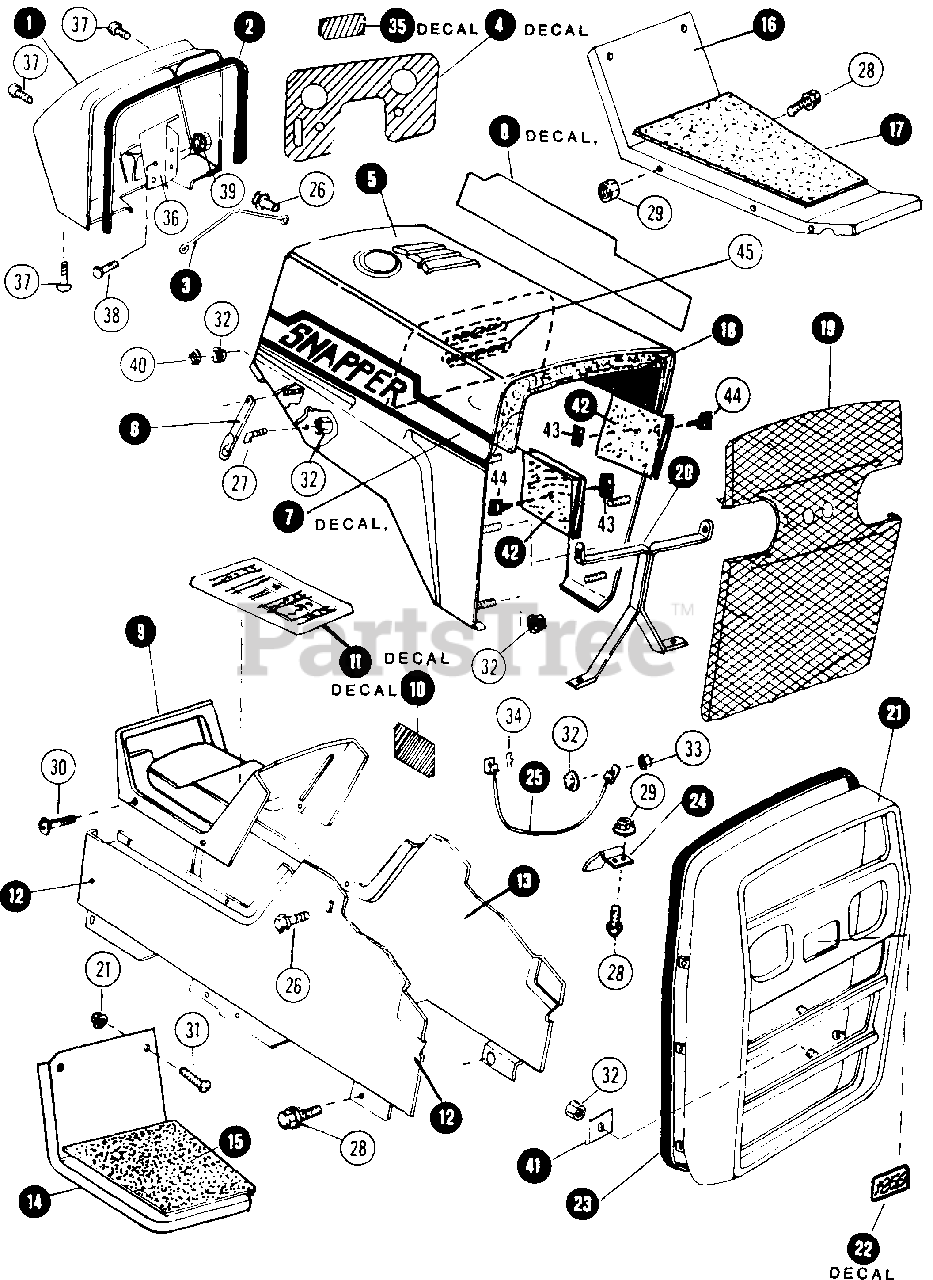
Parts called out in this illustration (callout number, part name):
1	COWL, INSTRUMENT DASH
2	TRIM, COWL MOLDING
3	REINFORCEMENT, COWL
4	DECAL, INSTRUMENT DASH
5	HOOD-PANEL
6	STRAP, HOOD RETAINER
7	DECAL, SNAPPER RIGHT SIDE HOOD
8	DECAL, SNAPPER LEFT SIDE HOOD
9	PANEL, CENTER ACCESS CONSOLE
10	DECAL, CAUTION
11	DECAL, CONSOLE - OPERATING INSTRUCTION
12	PANEL, RIGHT SIDE
13	PANEL, LEFT SIDE
14	PLATE, RIGHT STEP
15	TREAD, RIGHT PLATE
16	PLATE, LEFT STEP
17	TREAD, LEFT STEP PLATE
18	INSULATION, HOOD - PANEL
19	GRILLE - SCREEN ASSEMBLY
20	BRACE, HOOD
21	GRILLE - PANEL ASSEMBLY
22	DECAL, 1855 SERIES IDENTIFICATION
23	TRIM, HOOD - GRILLE MOLDING
24	HINGE, HOOD TILT
25	CABLE, HOLD TILT STOP
26	BOLT, 5/16F x 5/8 HEX FLANGE
27	LATCH, HOOD RETAINER STRAP
28	BOLT, 5/16C x 3/4 HEX FLANGE LOCK
29	NUT, 5/16C HEX FLANGE LOCK
30	SCREW, PAN HEAD 5/16C x 1/2
31	SCREW, 5/16C x 5/8 ROUND HEAD
32	NUT, 1/4C HEX FLANGE LOCK
33	NUT, 1/4C HEX LOCK
34	PIN, HAIR
35	DECAL, REFUEL CAUTION
36	BRACKET, COWL MOUNTING L.H.
37	SCREW, 5/16C x 3/4 ROUND HEAD
38	BOLT, 3/8C x 3/4 HEX
39	NUT, 3/8C HEX FLANGE LOCK
40	WASHER, 1/4 FLAT
41	WASHER, GRILLE SCREEN PLATE
42	INSULATION, HOOD SIDE
43	WASHER, SELF-LOCKING
44	ANCHOR, INSULATION
45	CUSHION, GAS TANK
